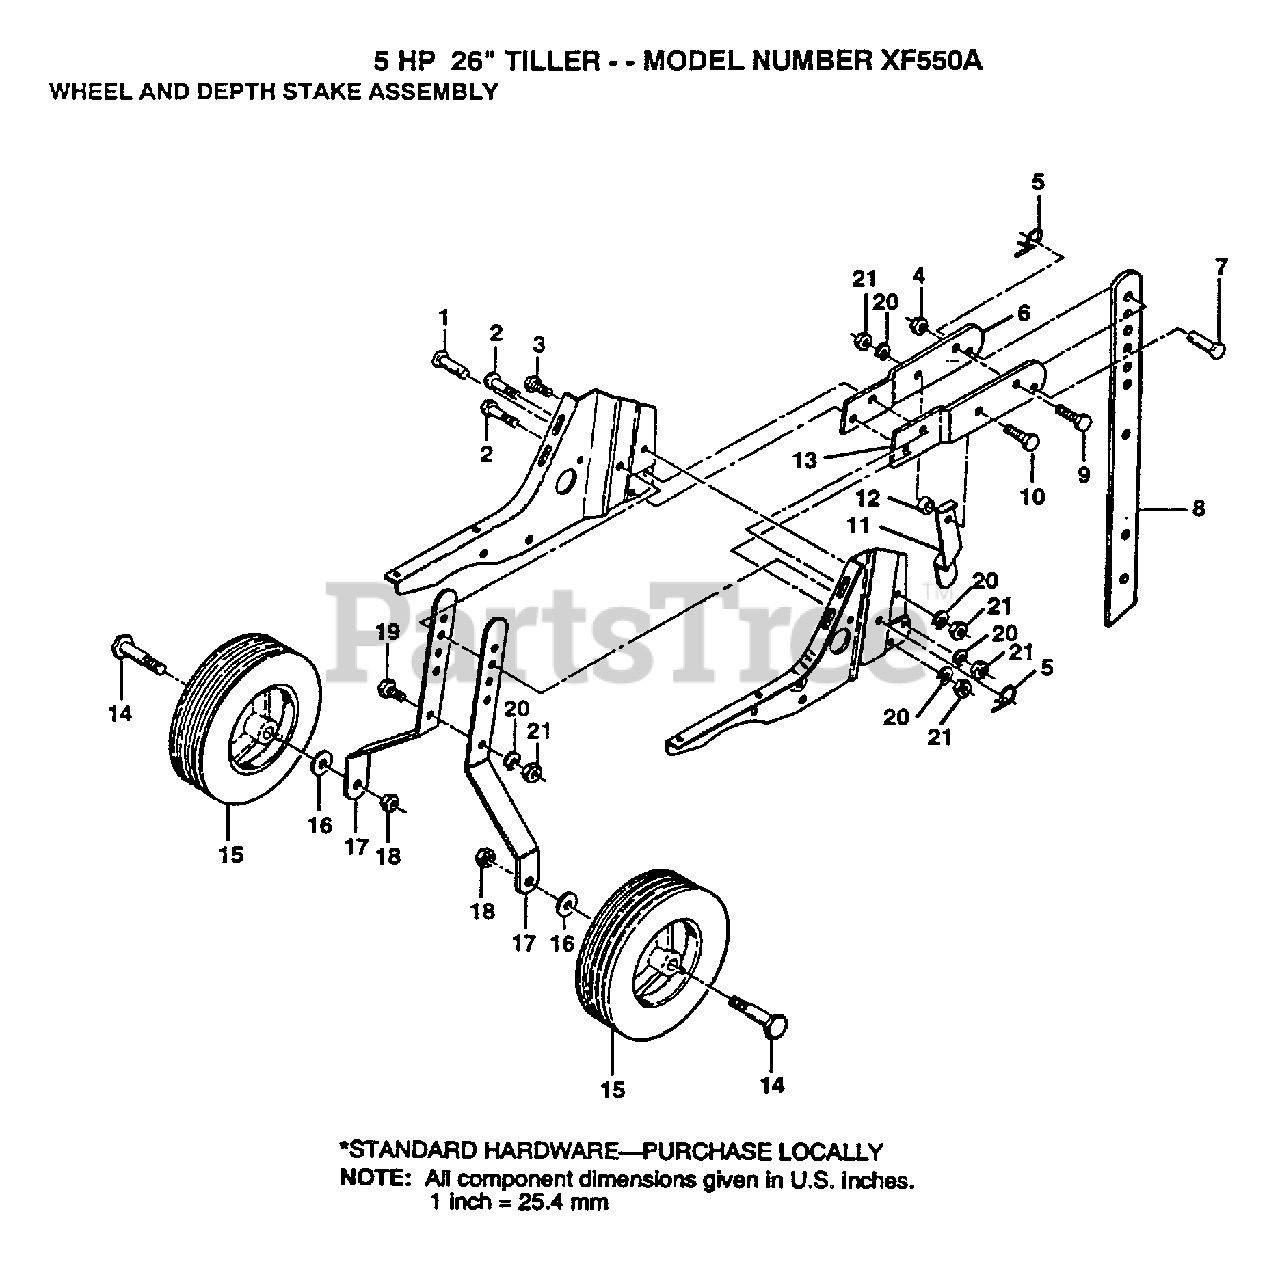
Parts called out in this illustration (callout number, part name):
1	DRILLED RIVET RT
3	BOLT
4	GRIPCO NUT
5	SPRING.RETAINER
9	BOLT.3/8-24X1-1/2
10	BOLT.HEX.5/16-1.5
11	STAKE SPRING TI
12	WASHER
14	BOLT SHOULDER
16	WASHER
20	LOCKWASHER
21	NUT.HEX.5/16-18
